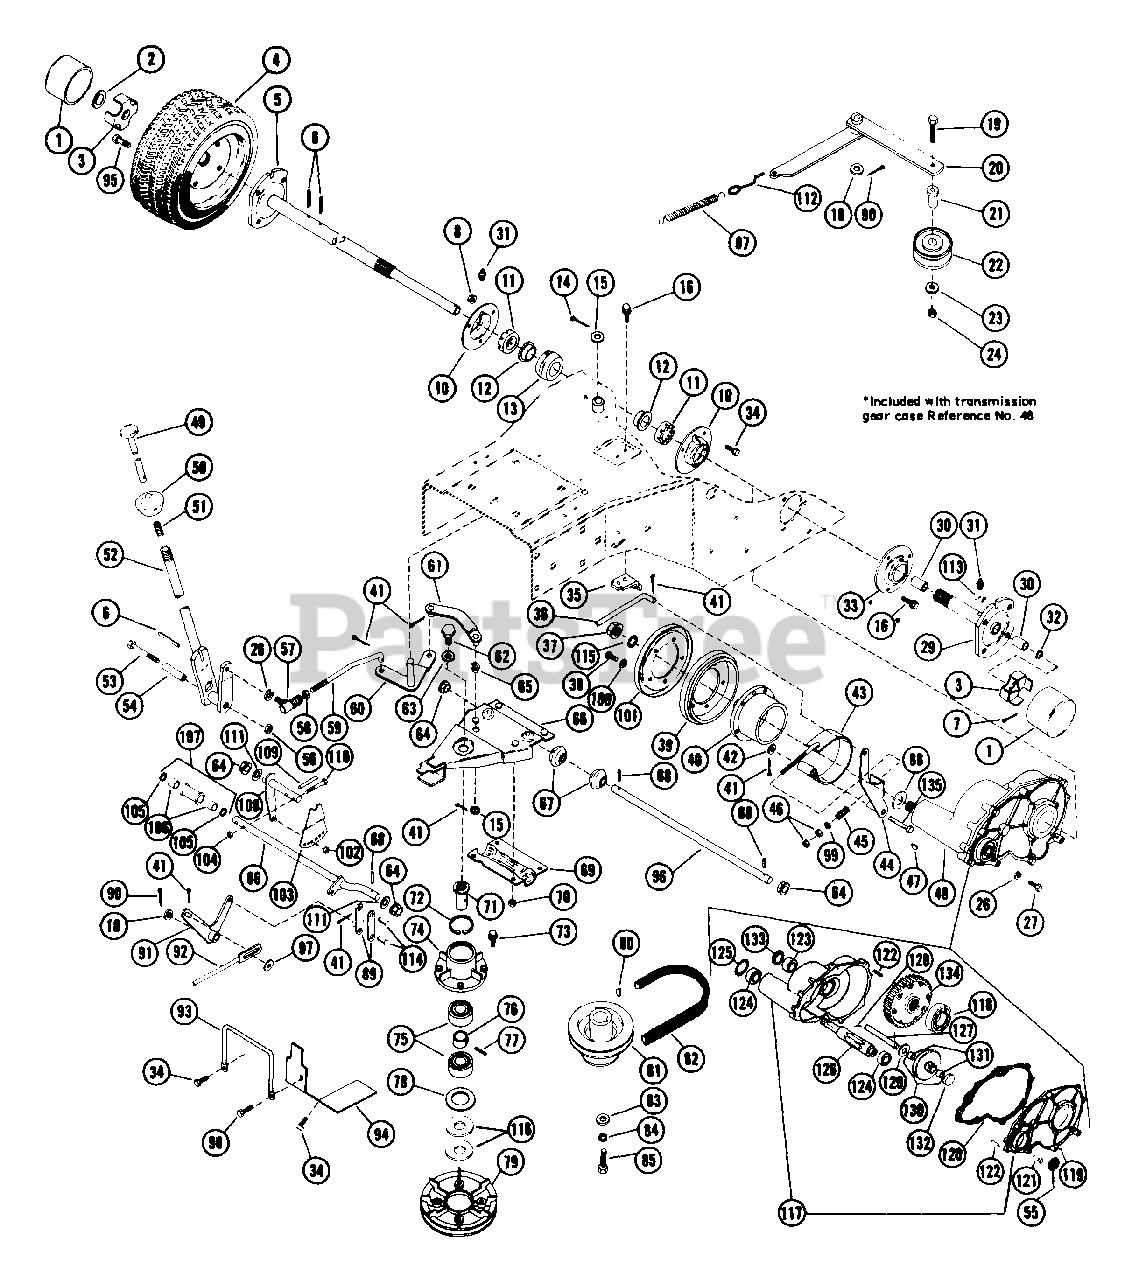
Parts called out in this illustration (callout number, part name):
1	HUB CAP
2	PUSHNUT
3	SPINDLE CUP
4	TERRA TIRE & WHEEL ASSEMBLY
5	R H AXLE SHAFT
6	PIN-ROLL .188X1.50
7	PIN-COTR .12 X 1.25 PL
8	NUT-LK-FLG .250-20 PL
10	BEARING FLANGE
11	ADJUSTMENT SPACER
12	BSHG-FLG 1.125X1.31X.50X1.62BR
13	SPHERICAL BUSHING
14	PIN-COTR .12X1.0 PL
15	WSHR-FL-STL .505X.880X.072 PL
16	BLT-SCRHFWH .25-20X.62 PL
18	WSHR-FL-STL .505X1.000X.062
19	BLT-HEX .31-18X1.25 PL GR2
21	SPCR, BRG .315X.50X.688X.281
22	IDLER
23	WSHR-FL-STL .38X.875X.083 PL
24	NUT-LK .312-18 GR A PL
26	WSHR-LK .312X.097 PL HVY
27	BLT-HEX .31-18X1.50 PL GR2
29	L H AXLE ASSEMBLY
30	BSHG-SLV .750X.814X .750 BRZ
31	SPIN DRIVE ZERK FITTING
32	O-RING .755X.950X.097
33	SEAL 1.125X2.496X.380
34	BLT-HEX .25-20X.50 PL GR2
35	NEUTRAL STOP
36	BRAKE ROD
37	NUT-LK-NYL.625-18 PL
38	BLT-HEX .31-18X.50 PL GR2
39	FRICTION DISC
40	FRICTION DISC HUB
41	PIN-COTR .09X.75 PL
42	WSHR-FL-STL .380X.626X.033
43	BRAKE BAND
44	BRAKE LEVER
45	SG-COMP .105X.585X.75
46	NUT-HEX .312-18
47	KEY-WDRF .188X.875X.375 SAE11
48	GEAR CASE ASSEMBLY
49	SHIFT CONTROL ROD
50	SHIFT BALL
51	SG-COMP ??X.44X?? WLD 10
52	SHIFT LEVER
53	BLT-HEX .38-16X2.50 PL GR2
54	SHIFT SPACER
56	NUT-LK-CTR .375-16 GR A PL
57	SNAP IN BALL JOINT
58	NUT-HEX .312-24 PL
59	SHIFT ROD
60	SHIFT LEVER
61	SHIFT LINK
62	SPINDLE STUD
63	WSHR-LK-EXT .500X.040 MED
64	FLANGE BUSHING
65	BSHG-FLG .372X.500X.312X.625NY
66	MTG PLATE
67	BEARING
68	PIN-ROLL .188X1.13
69	BEARING RETAINER
70	NUT-LK-CTR .250-20 PL
71	SPINDLE
72	SNAP RING KIT
73	BLT-SERHFWH .25-20X.75 PL
74	SPINDLE HOUSING
75	BRG-BALL .751X1.78X.61
76	SPACER .753X1.000X.457
77	PIN-ROLL .188X1.00
78	WSHR-FL-STL 1.375X2.125X.075
80	KEY-STR .25X2.0X.25
81	SHEAVE
82	V-BELT, SAE 380-RAW EDGE
83	WSHR-FL-STL .438X1.125X.19
84	WSHR-LK .375X.115 HVY PL
85	BLT-HEX .38-24X1.25 BLKO GR5
87	SG-TENS 5.65 FREE LENGTH
88	WSHR-FL-STL .627X.990X.032
89	LINK PLATE
90	PIN-COTR .09X1.0 PL
91	CLUTCH LEVER
92	CLUTCH ROD
93	BELT GUIDE
94	SPLASH GUARD
95	BLT-WHL .50-20X.75 GR5 PL
96	HINGE SHAFT
97	WSHR-FL-STL .382X.812X.023 PL
98	BLT-HEX .25-20X.75 PL GR2
99	WSHR-FL-STL .323X.625X.062 PL
100	WSHR-LK-INT .313X.030 PL
102	NUT-KEPS 8-32
103	STOP ADJUSTMENT
104	NUT-LK TOP .250-20 PL
105	SEAL .625X.875X.125
106	BSHG-SLV .625X.750X.500 BR
107	ROLLER ASSEMBLY
109	PIN-GRV .250X1.25 TP A
110	BLT-HEX .25-20X1.50
111	WSHR-FL-STL .630X1.005X.062 PL
112	SPRING HOOK
113	WSHR-LK .250X.047 LT PL
114	CLEVIS PIN
115	WSHR-LK-INT .625X.045 PL
116	WSHR-FL-STL 2.125X1.375X.005
117	COVER & CASE ASSEMBLY
118	BRG-BALL 1.125X2.50X.63
119	BREATHER
121	SCR-FLG-WHZ 10-24X.75 PL
122	PIN-GRV .188X.63
123	BSHG-SLV 1.125X1.375X.625
124	BRG-BALL .625X1.375X.44
125	RG-RTNG-INT 1.375X.050
126	PINION SHAFT
127	IDLER SHAFT
128	PIN-ROLL .125X.75
129	WSHR-FL-STL .505X1.000X.062
130	PINION & GEAR W/BEARING ASSEMB
131	BRG-NEEDLE .50X.688X.625
132	SPACER .507X.875X.289
133	SEAL 1.125X1.624X.250
134	DIFFERENTIAL ASSEMBLY
